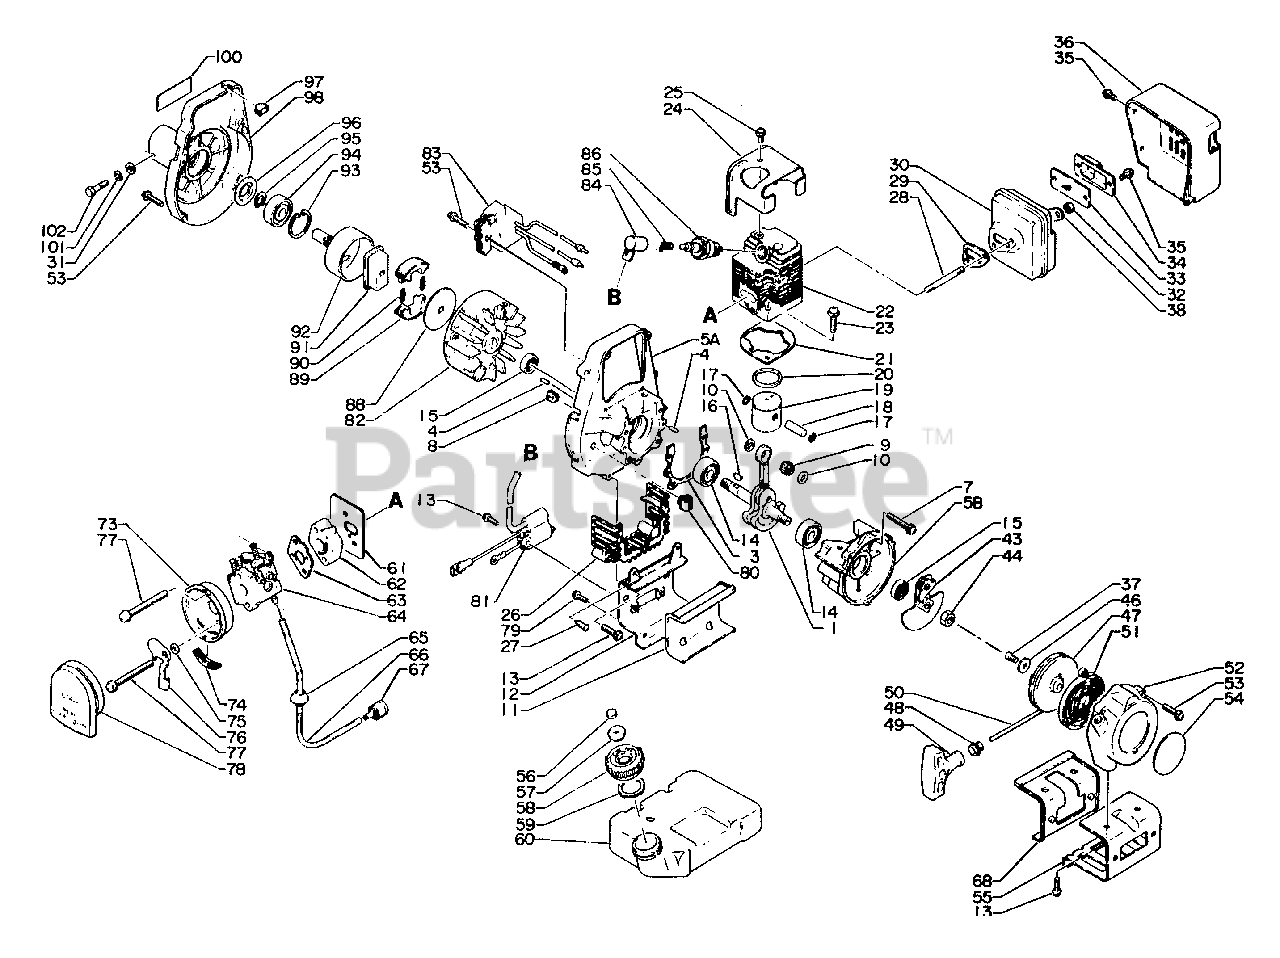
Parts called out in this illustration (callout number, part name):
1	CRANKSHAFT ASSY
3	GASKET, CRANKCASE
4	PIN, LOCATING 4
5	CRANKCASE KIT
5A	CRANKCASE KIT
5B	CRANKCASE KIT
7	SCREW 5×30
9	BEARING, NEEDLE
10	WASHER, THRUST
11	CUSHION
12	BRACKET, FUEL TANK
13	SCREW 4×14
14	BEARING, BALL - 6201 C3
15	SEAL, OIL 12
17	RING, SNAP
18	PIN, PISTON
19	PISTON
20	RING, PISTON
21	GASKET, CYLINDER
22	CYLINDER
23	SCREW 6×20
24	COVER, CYLINDER
25	SCREW 5×10
26	SEAL, DUST
27	SCREW 4×14
28	BOLT, STUD
29	GASKET, EXHAUST
30	MUFFLER
31	WASHER, FLAT 5.5×10×0.8
32	LOCKNUT - 5
33	SCREEN, SPARK ARRESTER
34	SCREEN HOLDER
35	SCREW 4×10
36	COVER, MUFFLER
37	SCREW - 4×10
38	WASHER
43	PAWL ASSY, STARTER
44	NUT 8×1.25
46	WASHER
47	REEL, ROPE
48	ROPE, STARTER 3.0×850
49	GRIP, STARTER
50	GUIDE, ROPE
51	SPRING, RECOIL
52	CASE, STARTER
53	SCREW 4×20
54	LABEL - ECHO
55	BRACKET, FUEL TANK
56	FILTER, CHECK VALVE
57	VENT ASSY
58	CAP
60	TANK, FUEL
61	GASKET, INTAKE
62	INSULATOR, INTAKE
63	GASKET, INTAKE
64	CARBURETOR - WA-81
66	PIPE, FUEL 3×5×150 BLACK
67	FILTER, FUEL
68	CUSHION
73	CASE, AIR FILTER
75	WASHER 5.2×8×0.8T
76	SHUTTER, CHOKE
77	SCREW 5×57
78	FILTER, AIR
79	SCREW 4×12
80	CLAMP
81	COIL, IGNITION
82	FLYWHEEL
83	COIL, IGNITION
84	CAP, SPARK PLUG
85	TERMINAL, SPARK PLUG
86	SPARK PLUG - CJ8
88	PLATE, CLUTCH
89	SHOE, CLUTCH
90	SPRING, CLUTCH
91	BOSS, CLUTCH
92	DRUM, CLUTCH
93	RING, SNAP Ø32
94	BEARING, BALL 6201
95	RING, RETAINING - 12
96	STOPPER, PIPE
97	PLUG
98	COVER, FAN
100	LABEL - MODEL
101	WASHER, SPRING 5
102	BOLT 5×25
